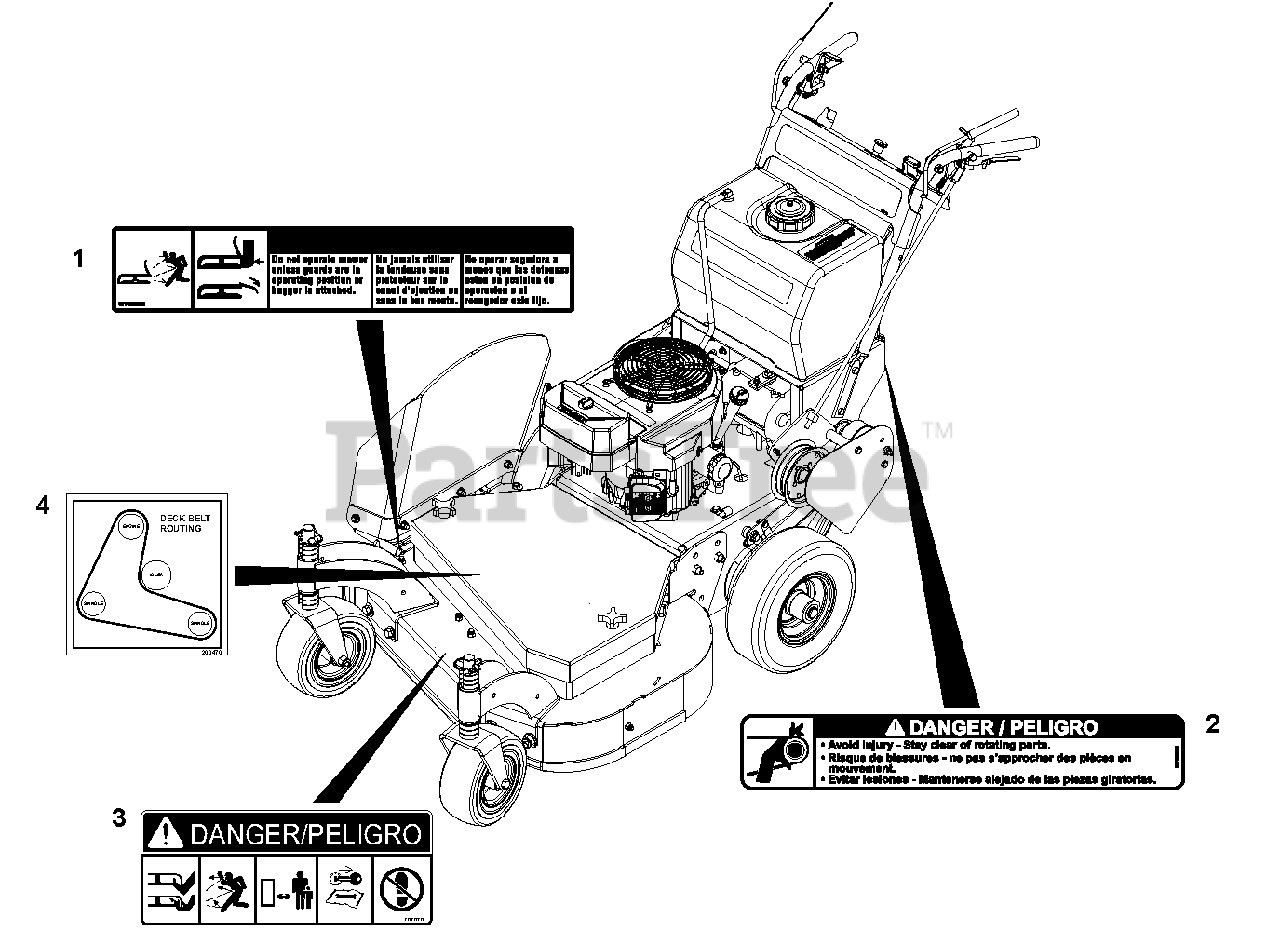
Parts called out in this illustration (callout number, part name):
1	Decal, Warning
2	Decal, Danger-Belt Rotating
3	Decal, Mower Pan Danger
4	Decal, Deck Belt Routing (410, 411)
